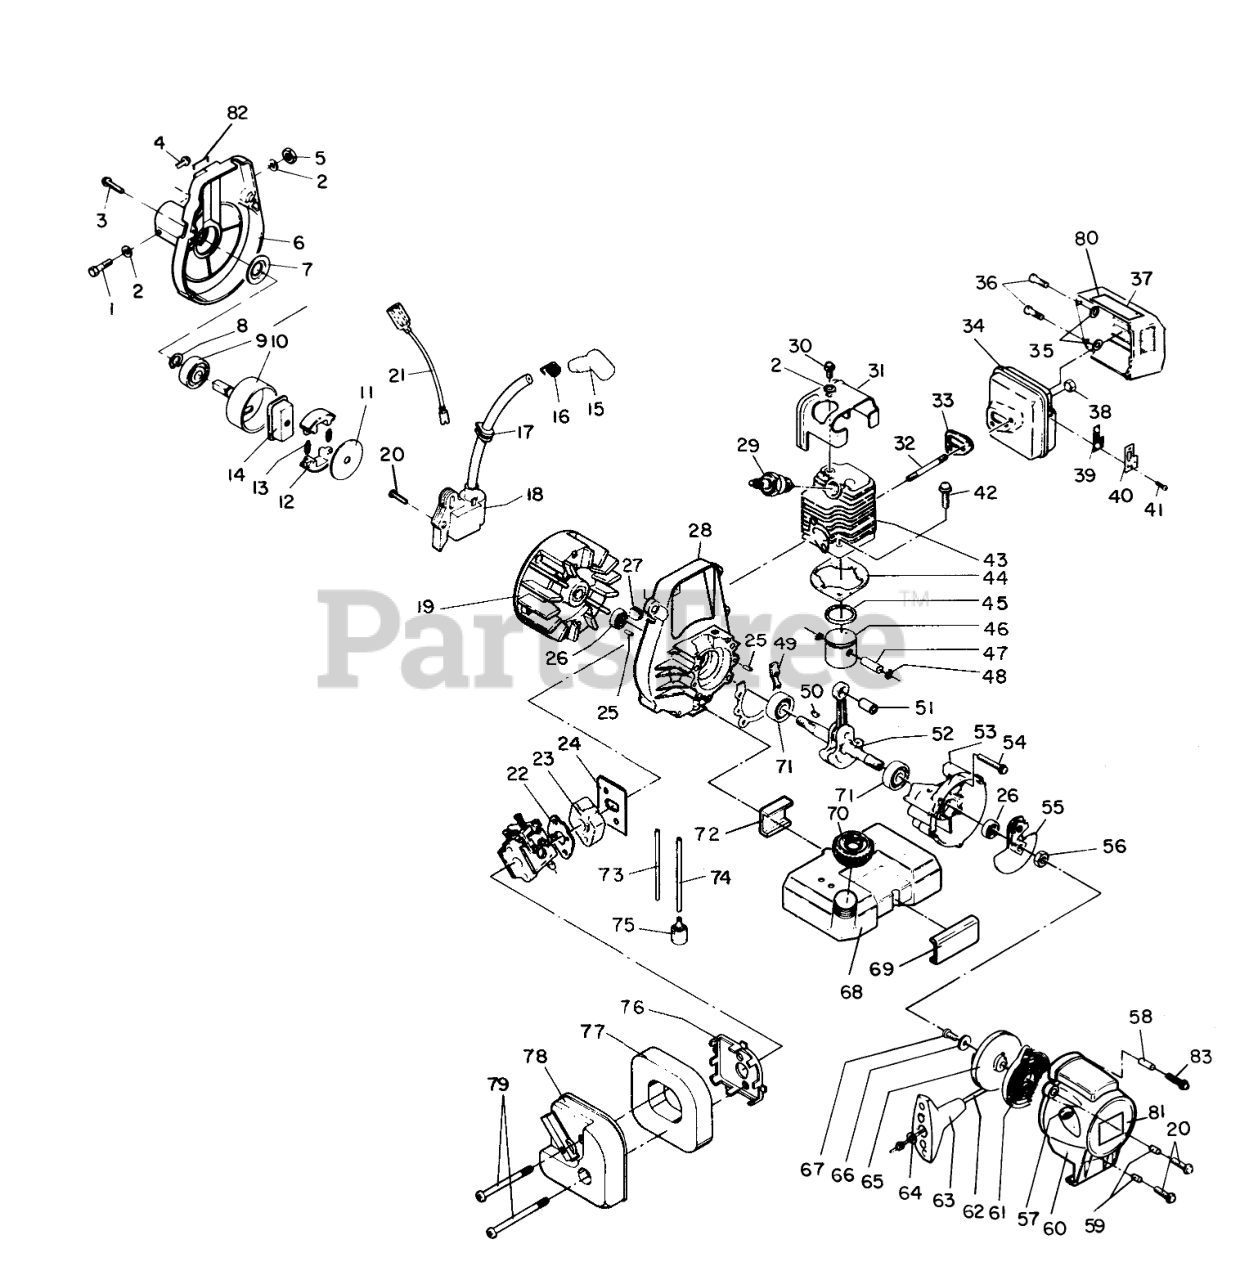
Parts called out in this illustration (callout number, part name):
1	Screw-Engine Clamp
2	Washer-Flat
3	Screw-Rotor
4	Screw-Jams
5	Nut-Engine Clamp
6	Housing-Fan
7	Plate-Thrust
8	Ring-Retaining
9	Bearing-Ball
10	Clutch-Drum
11	Plate-Side
12	Clutch-Shoe
13	Spring
14	Rotor
15	Boot-Spark Plug
16	Connector-Spark
17	Grommet
19	Flywheel
20	Screw-Coil
21	Wire Assembly-Switch
22	CARBURETOR GASKET
23	Insulator-Carburetor
24	Gasket-Insulator
25	Pin-Dowel
26	Seal-Crankshaft
27	Grommet
28	Crankcase Assembly (Incl.Ref. #53)
29	Spark Plug
30	Screw
31	CYLINDER COVER
32	Stud-Muffler
33	MUFFLER GASKET
34	Muffler Assembly
35	Spacer-Heat Shield
36	Screw
37	Shield-Heat
38	Nut-Muffler
39	Screen-Spark Arrester
40	Cover-Screen
41	Screw
42	Screw-Cylinder
43	Cylinder
44	CYLINDER GASKET
45	Ring-Piston
46	Piston
47	Pin-Wrist
48	Ring-Snap
49	Gasket-Crankcase
50	Key-Flywheel
51	Bearing-Needle
52	Gasket
53	Crankcase (Incl. Ref. #28)
54	Screw
55	Ratchet Ass-y-Recoil
56	Nut-Hex
57	Guide-Rope
58	Spacer-Heat Shield
59	Spacer-Recoil
60	Housing-Recoil (Incl. Ref. #57)
61	Spring-Recoil
62	Rope-Recoil
63	Handle-Recoil
64	Washer-Recoil Rope
65	Pulley
66	Washer-Flat
67	Screw
68	Tank Assembly (Incl. Ref. #73-75)
69	Pad-Fuel Tank
70	Cap-Fuel
71	Bearing-Main Ball
72	Pad-Fuel Tank
73	Hose-Fuel Return
74	Hose-Fuel Carb.
75	FUEL FILTER
76	Box-Air Cleaner
77	Filter-Air (Foam)
78	Cover-Choke
79	Screw-Choke Lever
80	DECAL-SURFACE, HOT
81	DECAL
82	DECAL-SURFACE, HOT
83	Screw
